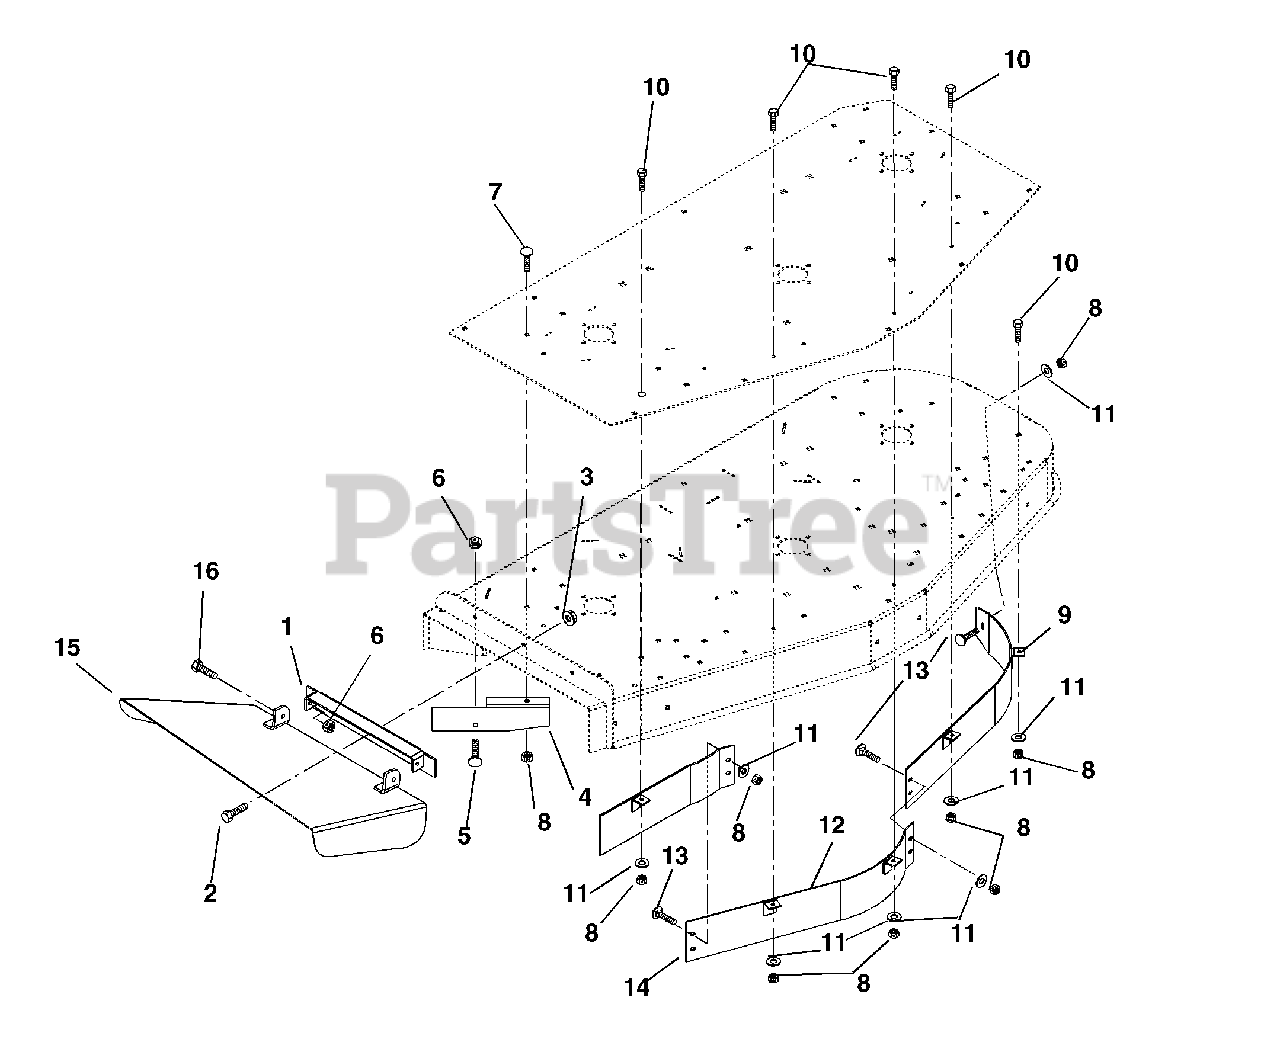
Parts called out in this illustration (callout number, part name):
1	Weldment, Discharge Chute Bracket
2	Bolt-Hex .38-16 x 1.00 Grade 5
3	Nut-Locking-Flange .38-16
4	Deflector, 60
5	Bolt-Round Head Square Neck .38-16 x 1.00 Grade 2
6	Nut-Locking-Center .38-16
7	Bolt-Round Head Square Neck .31-18 x 1.00 Grade 5
8	Nut-Locking-Nylon .31-18
9	Weldment, 60" Left Hand Baffle-Upper
10	Bolt-Hex .31-18 x 1.00 Grade 5
11	Washer-Flat-Steel .312 x .734 x .065
12	Weldment, 60" Center Baffle-Up
13	Bolt-Round Head Square Neck .31-18 x .75 Grade 5
14	Weldment, 60" Right Hand Baffle-Upper
15	Weldment, Discharge Chute 60"
16	Bolt-Hex .38-16 x 1.00 Grade 5
17	60" Discharge Cover
18	60" Mulch Kit
